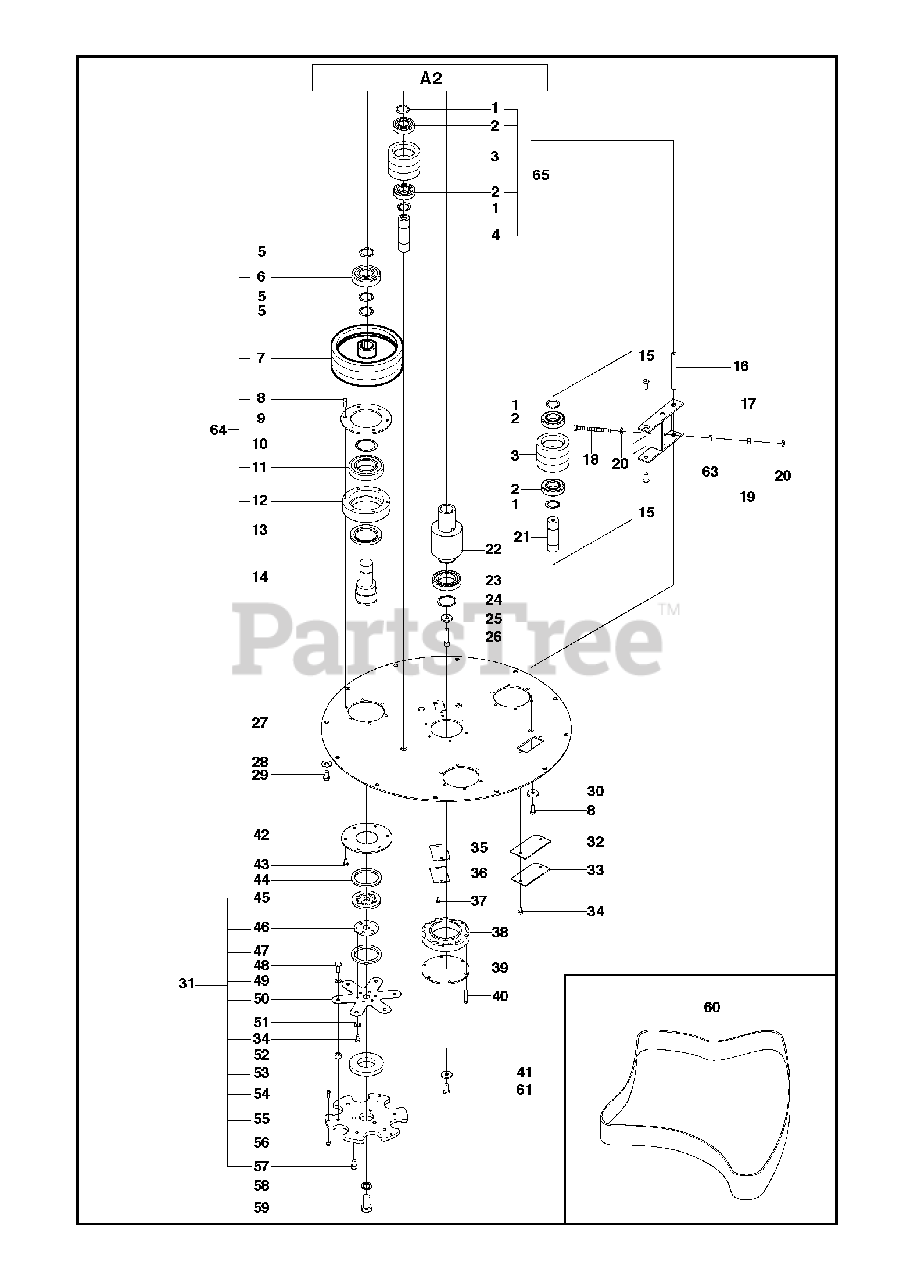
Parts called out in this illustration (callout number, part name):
20	WASHER
28	WASHER
49	WASHER
51	WASHER
63	HEXAGON LOCKING NUT
